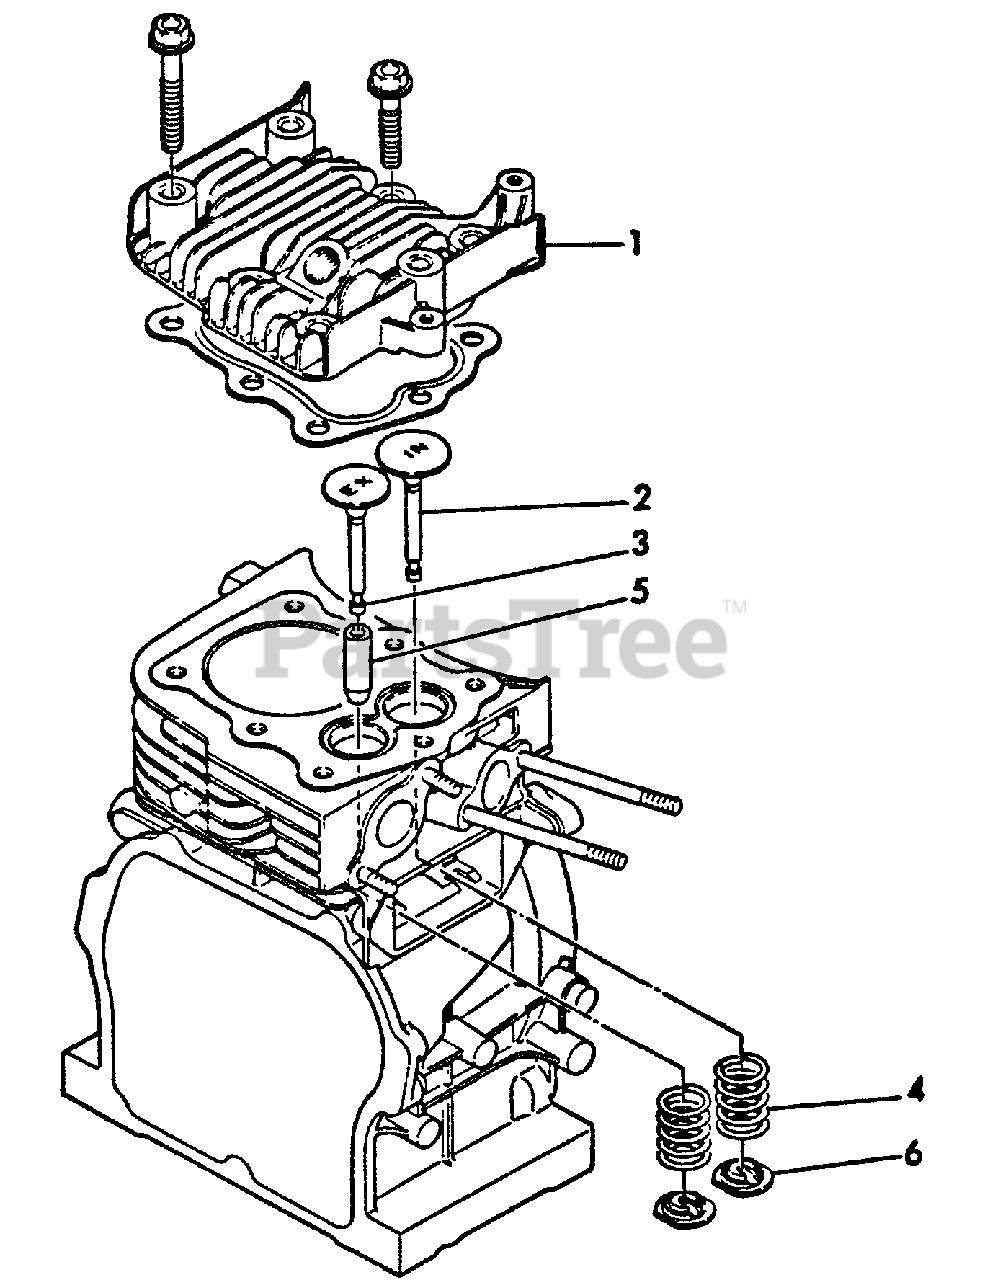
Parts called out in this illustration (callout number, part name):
1	HEAD, CYLINDER
2	VALVE, SUCTION
3	VALVE, EXHAUST
4	SPRING, VALVE
5	GUIDE, VALVE
6	RETAINER, SPRING
